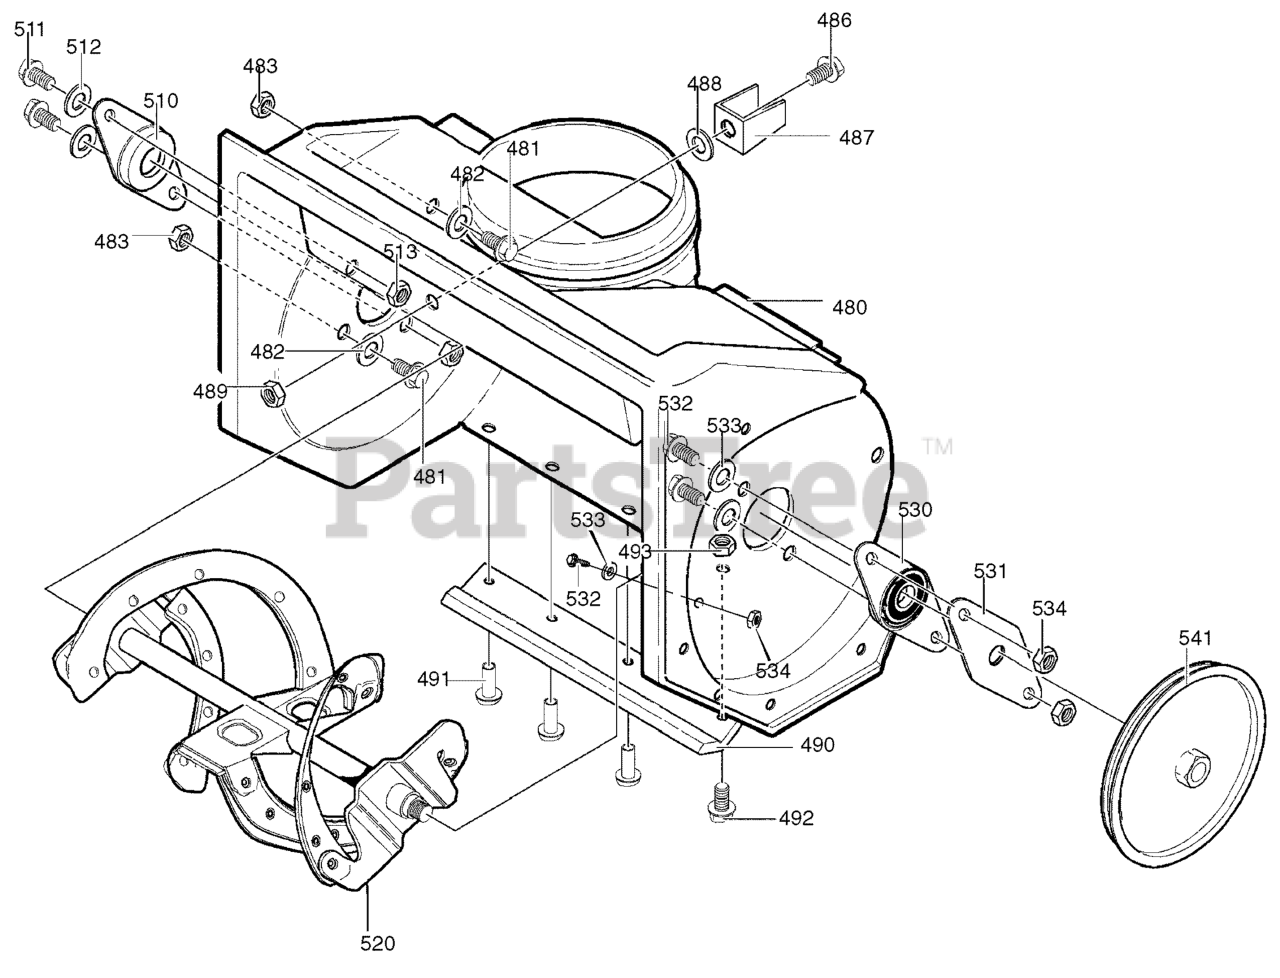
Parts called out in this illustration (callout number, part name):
480	HOUSING, ASSY
481	SCREW, 1/4-20X.75
482	WASHER, FLAT .281X.63X.065
483	NUT, HEX 1/4-20 YZ
486	SCREW, 1/4-20X.63
487	BRACKET, STOP
488	WASHER, FLAT .333X.87X.119
489	NUT, 1/4-20 HEX NYLOCK
490	BLADE, SCRAPER
491	RIVET, OVSET
492	SCREW, 1/4-20X.75
493	NUT, 1/4-20 YZ
510	BEARING, FLANGE
511	SCREW, 1/4-20X1.00
512	WASHER, FLAT .281X.63X.065
513	NUT, 1/4-20
520	AUGER, ASSY
520-2	BLADE, AUGER
520-6	RIVET
520-8	BLADE, CENTER
520-10	AUGER & BLADE SUPPORT
530	BEARING & PLATE ASSY
531	PLATE, RETAINER
532	SCREW, 1/4-20X.63
533	WASHER, FLAT .281X.63X.065
534	NUT, 1/4-20
